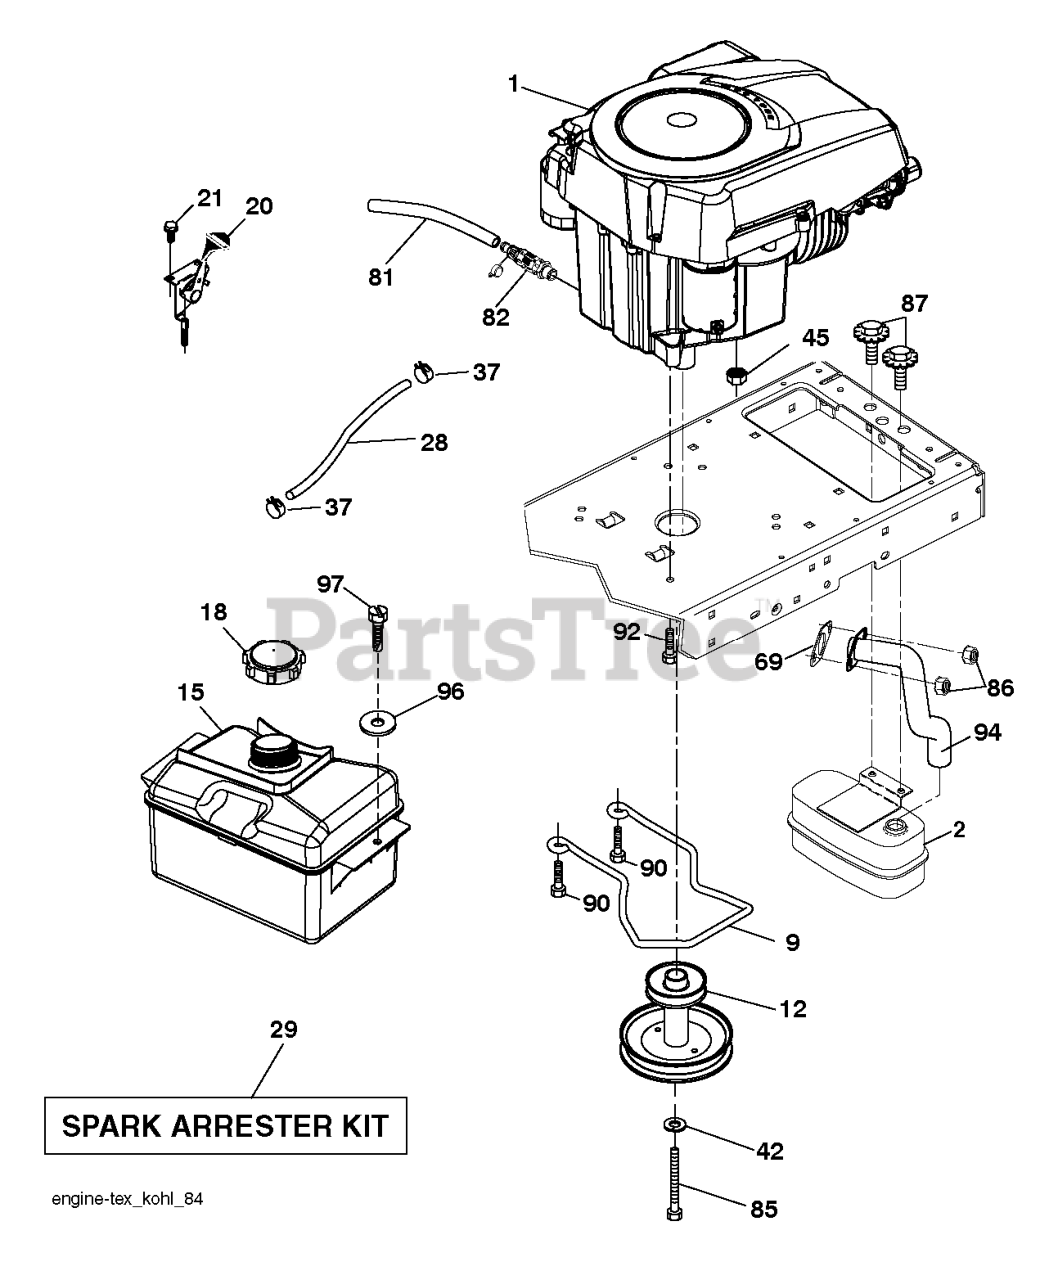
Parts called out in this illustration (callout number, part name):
2	MUFFLER.ASM.SINGLE
9	KEEPER.BELT.ENG.3.25"2BOLT.PNT
12	PULLEY.ENGINE
18	CAP ASM.FUEL.2.25"FR.
20	CONTROL.TH/CK.COBRA.KO
21	SCREW.#10 X 0.750.BOS
28	LINE.FUEL.20
29	KIT.SPARK ARRESTOR 794945 B&S
37	HOSE CLAMP
42	WASHER 7/16 LOCK
45	NUT
69	GASKET.EXHAUST.KOHLER
81	TUBE, DRAIN OIL ASM.
82	VALUE.OIL.DRAIN
85	BOLT.HEX.7/16-20X4.GR5.1.5BLUE
86	NUT.HEX.FLANGE.TOPLOCK
87	BOLT.5/16-18UNCX3/4 W/SEMS.BLK
90	SCREW 3/8-16X1
92	SCREW 3/8-16X1
94	TUBE.EXHAUST.KOHLER 5400
97	SCREW HEXWSHR 1/4-20X3/4
